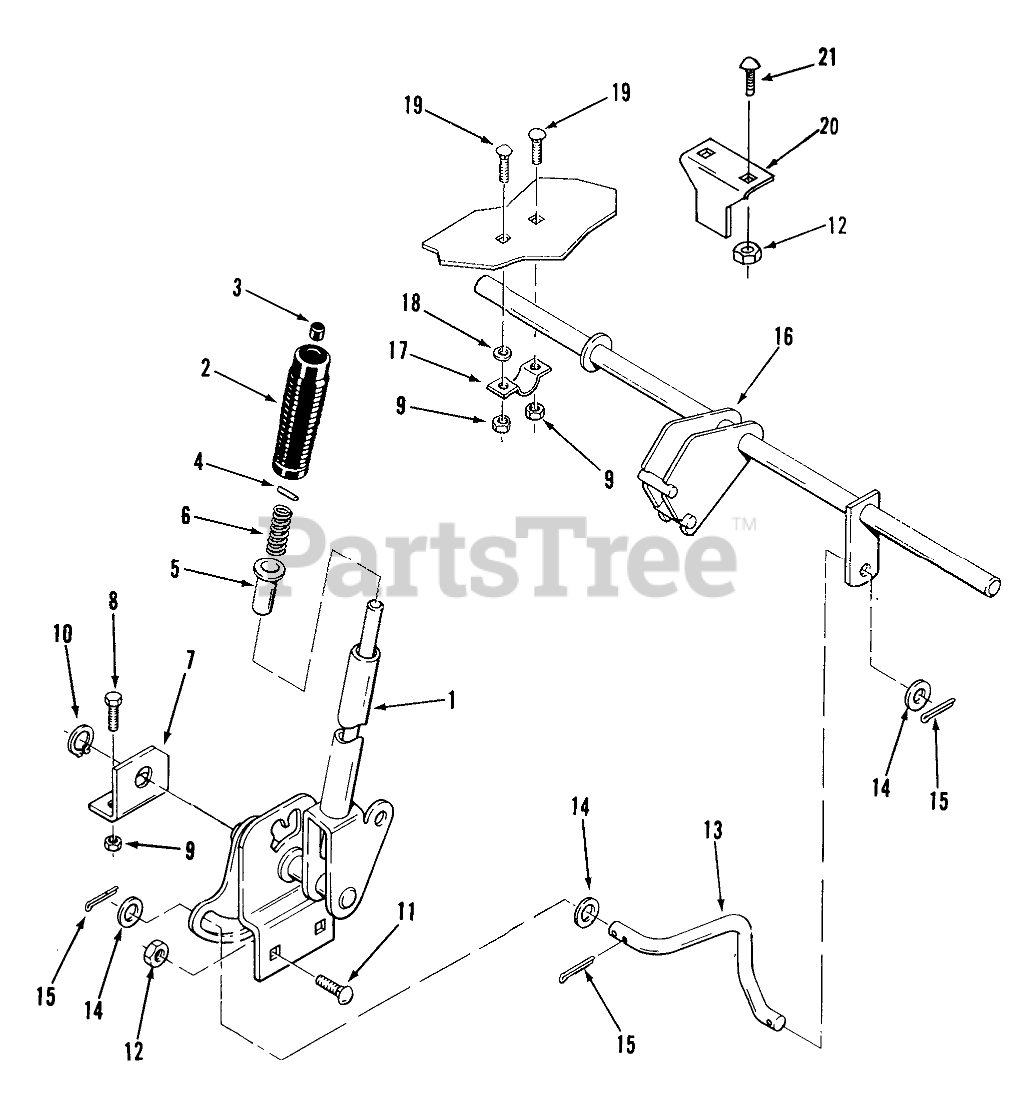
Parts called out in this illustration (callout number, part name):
1	Lift Lever
2	HANDGRIP
3	CAP-ROD, PLUNGER
4	PIN-SPIROL
5	RETAINER-SPRING
6	SPRING-COMPRESSION
7	BRACKET-INNER R
8	Bolt
9	Nut
10	Snap Ring
11	Bolt-Carriage
12	NUT
13	ROD-LIFT R
14	Washer
16	ASM-REAR LIFT R
17	CLAMP
18	Washer
19	SCREW
20	BRACKET STOP
21	Bolt
